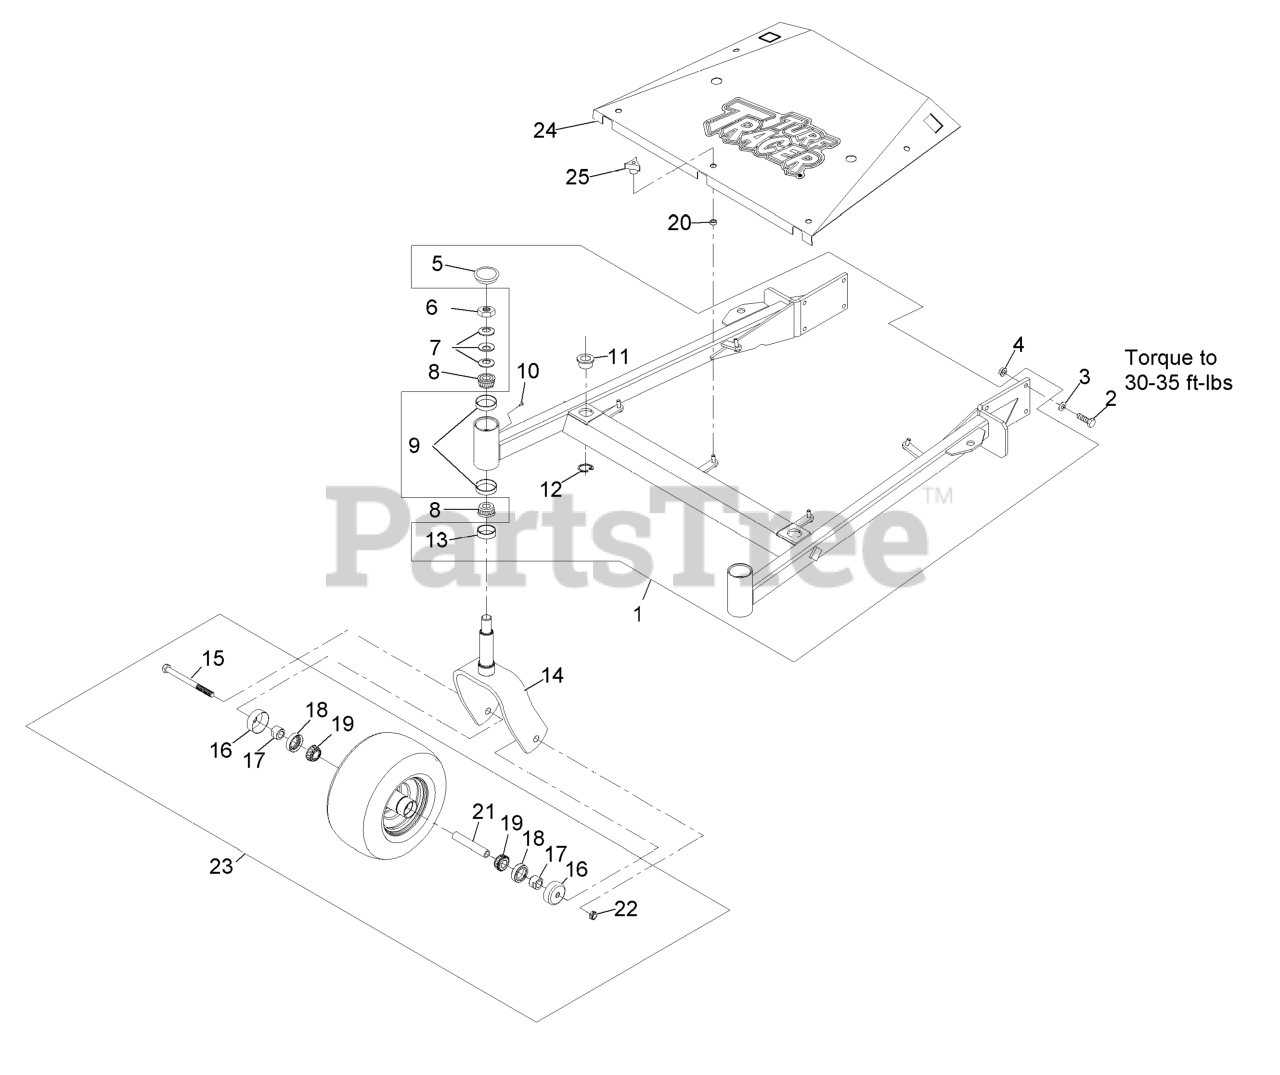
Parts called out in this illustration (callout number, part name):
1	ASM,FMD604 DK SUPPORT, SE
2	SCREW-HH
3	WASHER-BELLEVILLE
4	NUT-HHF, WHIZ
5	CAP-GREASE
6	NUT-LOCK, NI
7	WASHER-BELLVILLE
8	Cone-Bearing Tapered Roller
9	CUP-BEARING
11	BUSHING-DECK
12	RING-RETAINING
13	SEAL-GREASE
14	WLD, CASTER FORK
15	SCREW-HH
16	GUARD-SEAL
17	SPACER-NUT
18	SEAL-CASTER
19	BEARING-CONE, TAPERED ROLLER
22	NUT-HEX
23	ASM,WHEEL&BEARINGS
24	KIT,SHIELD TT604 W/ DECAL
25	KNOB-3 PRONG
